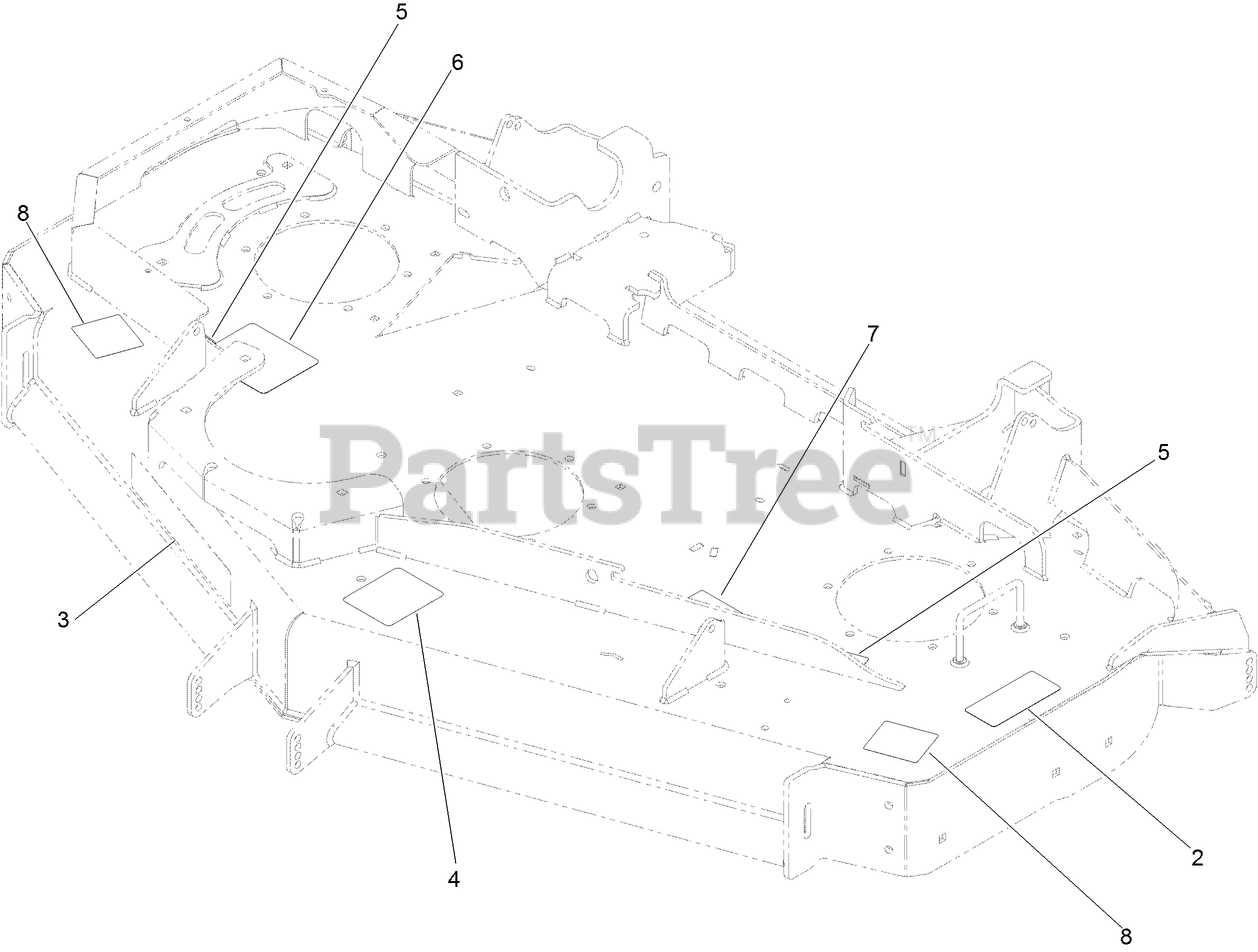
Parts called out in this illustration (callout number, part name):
2	DECAL-TORQUE, BLADE BOLT
4	DECAL-ROLLER, ANTI-SCALP
5	DECAL-COVER, MISSING
6	DECAL-SPINDLE, COUNTER ROTATING
7	DECAL-BELT ROUTING REAR
8	DECAL-DANGER, THROWN OBJECT
